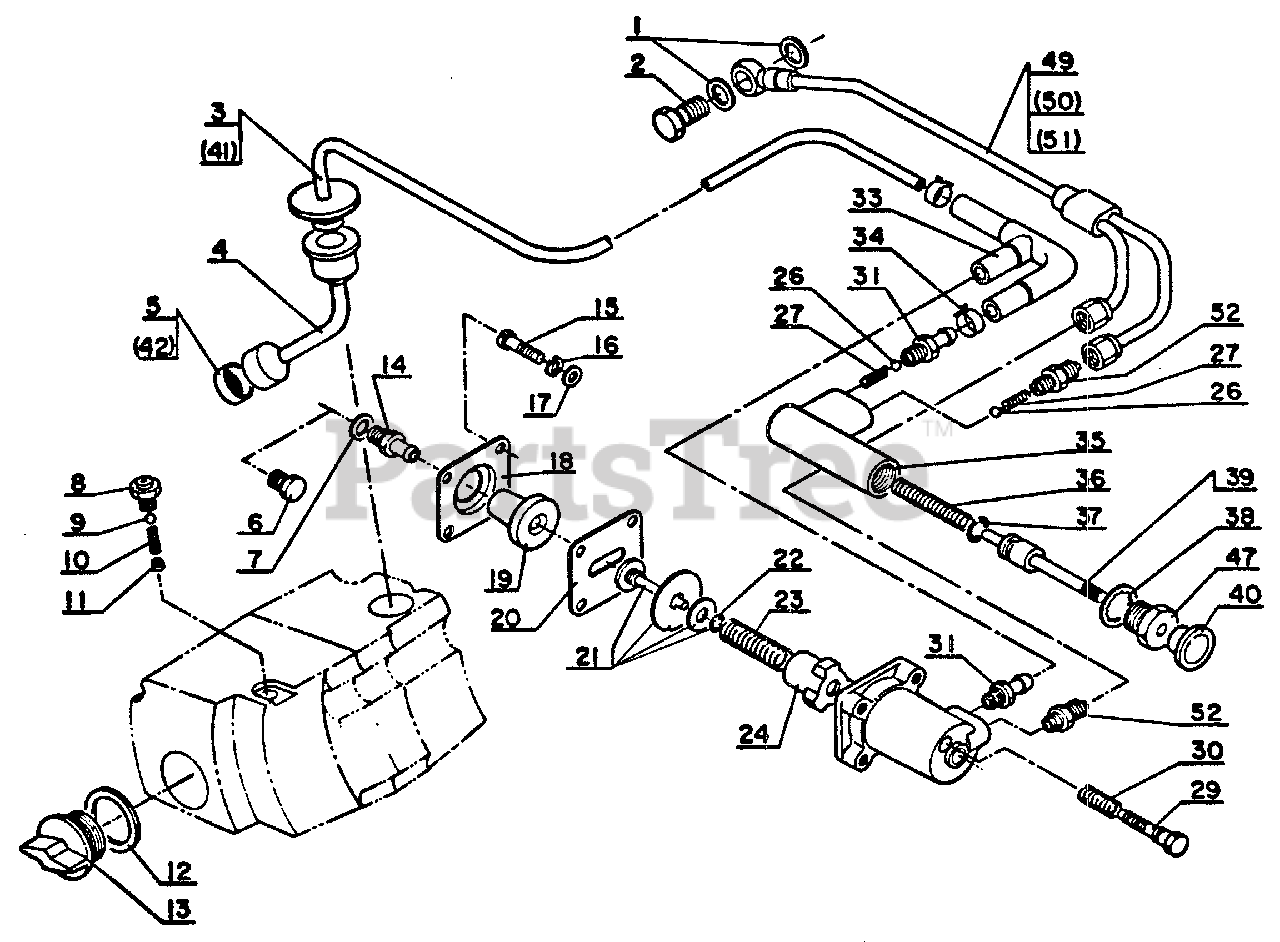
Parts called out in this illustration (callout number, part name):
1	GASKET
3	PIPE - OIL
4	PIPE, OIL - INNER
5	FILTER, OIL
8	Nut, air breed
9	VALVE, BALL
10	SPRING, AIR BLEED
11	Plug, air breed
12	GASKET, CAP
13	CAP, OIL TANK
15	SCREW - 4X15
16	LOCKWASHER - 4
17	WASHER - 5
18	RETAINER
19	CONNECTOR
21	PLUNGER ASSY
22	O-RING - 3
23	SPRING, ADJUST
24	CASE, SPRING
26	VALVE, BALL
27	SPRING, VALVE
29	SCREW, ADJUST
30	SPRING
31	CONNECTOR
33	PIPE - OIL
34	CLIP
35	BODY, OIL PUMP
36	SPRING, OIL PUMP
37	O-RING - 6
38	LOCKWASHER
39	PISTON, OIL PUMP
40	BUTTON, OIL PUMP
49	PIPE - OIL
52	CONNECTOR
